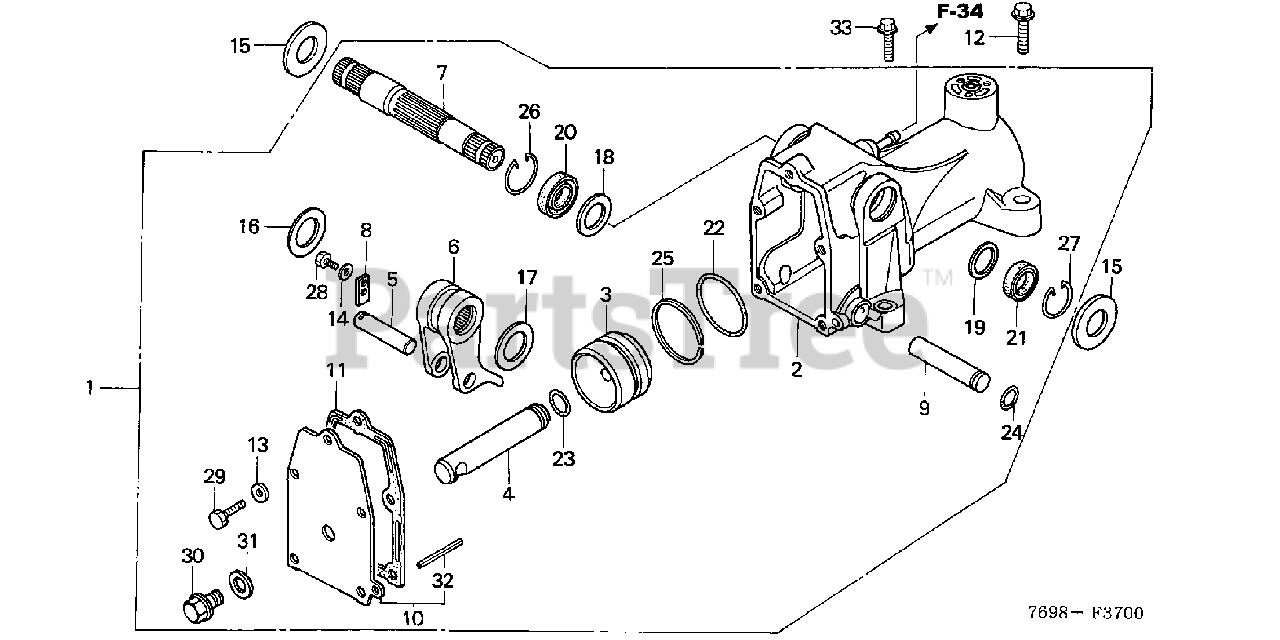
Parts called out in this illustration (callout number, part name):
1	CYLINDER ASSY., HYDRAULIC
1	CYLINDER ASSY., HYDRAULIC Use up to Frame SN 2500167.
2	CYLINDER, HYDRAULIC
3	PISTON, HYDRAULIC (60MM)
4	ROD, CONNECTING
5	PIN, CONNECTING ROD
6	ARM, HYDRAULIC CYLINDER
7	SHAFT, HYDRAULIC CYLINDER
8	PLATE, CONNECTING ROD PIN
9	SHAFT, STOPPER
10	COVER, CYLINDER
11	GASKET, HYDRAULIC CYLINDER COVER
12	BOLT, FLANGE (12X58)
12	BOLT, FLANGE (12X50)
13	WASHER (8MM)
14	WASHER, CONICAL SPRING (6MM)
14	WASHER, THRUST (25.5X50X5)
15	WASHER, THRUST (25.5X50X5)
16	WASHER, PLAIN (INNER) (28.5MM)
17	WASHER, PLAIN (INNER) (25.5MM)
18	WASHER, PLAIN (OUTER) (30.5MM)
19	WASHER, PLAIN (OUTER) (25.5MM)
20	OIL SEAL (30X44X8)
21	OIL SEAL (25X38X9)
22	O-RING, HYDRAULIC CYLINDER
23	O-RING (17X3.5)
24	O-RING (13.8X2.4)
25	RING, BACK-UP
26	RING, STOPPER (49)
27	RING, STOPPER (43)
28	BOLT, HEX. (6X12)
29	BOLT, HEX. (8X22)
30	BOLT, DRAIN PLUG (14MM)
31	WASHER, DRAIN PLUG (14MM)
32	PIN, SPRING (6X40)
33	BOLT, FLANGE (10X55)
